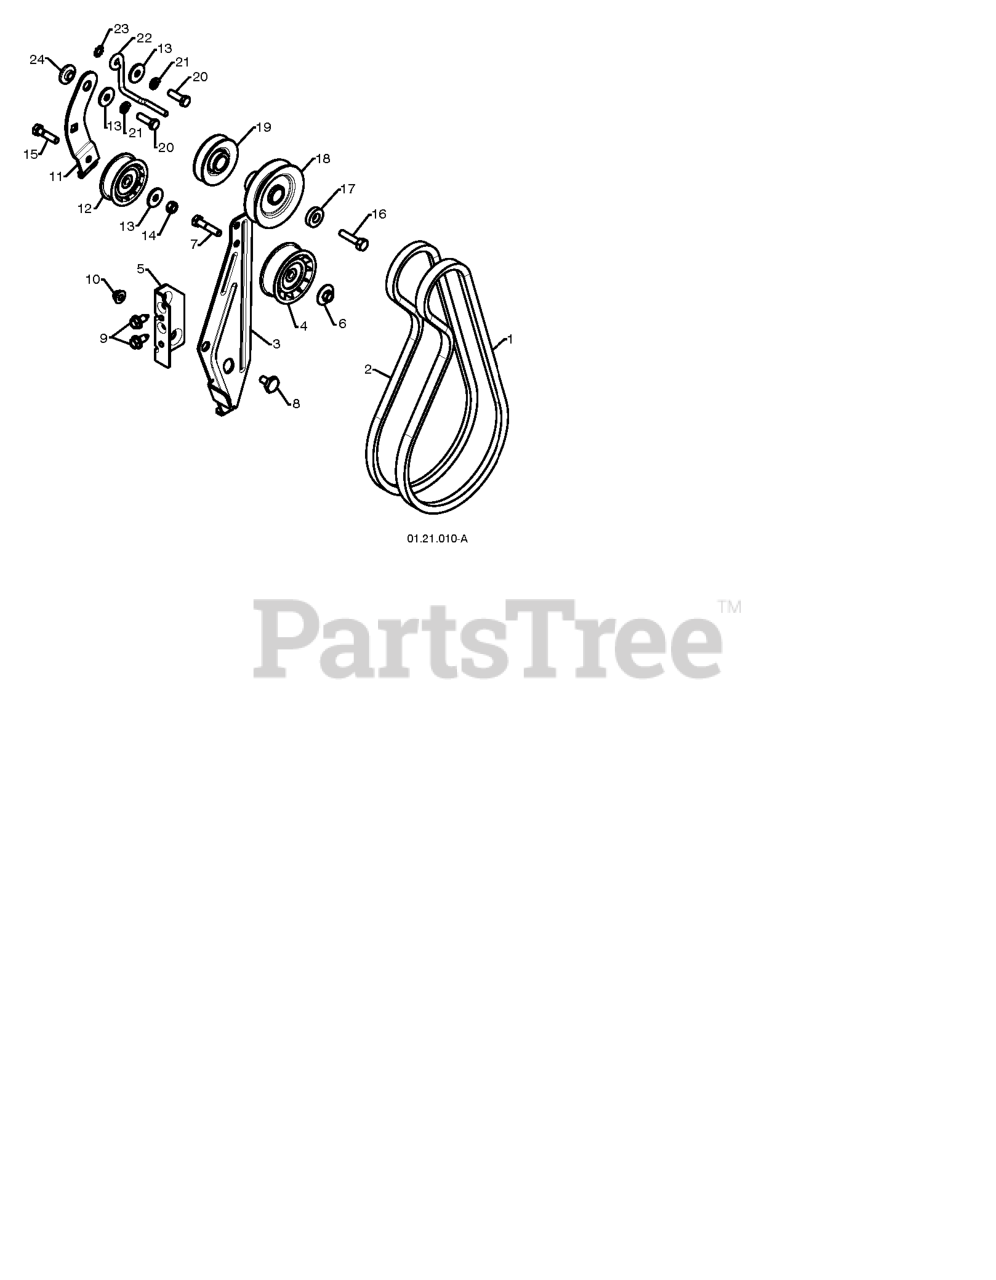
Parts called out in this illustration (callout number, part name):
1	VBELT; IMPELLER_39.09
2	V-BELT.TRACTION.HYDRO
3	ARM.IDLER.BRAKE.
4	PULLEY.W/SPACER.2.75
5	RP BRACKET.IDLER.PIVOT
6	NUT.FLANGE.HEX.5/16X18.BLACK
7	HEX BOLT
8	BOLT.SHOULDER.1/2X12
9	BOLT.HEX.HD.WASHER.5/16-18X.75
10	NUTNYLOK.FLRANGE.5/16-18
11	ARM, IDLER
12	PULLEY.W/SPACER.2.25
14	NUT.CENTERLOCK.5/16-
15	BOLT.5/16-18X1-1/4 FULL.THREAD
16	SCREW, HEX HD 3/8-24 X 1-3/8
17	WASHER, FLAT 3/8
18	PULLEY.ENG.IMPELLER.SNOW
19	PULLEY.ENG.TRACTION
21	WASHER.LOCK.HVY.HLCL.SPR.5/16
22	GUIDE, BELT
23	WASHER EXT TOOTH LOCK 5/16
24	RP BUSHING, IDLER PIVOT
